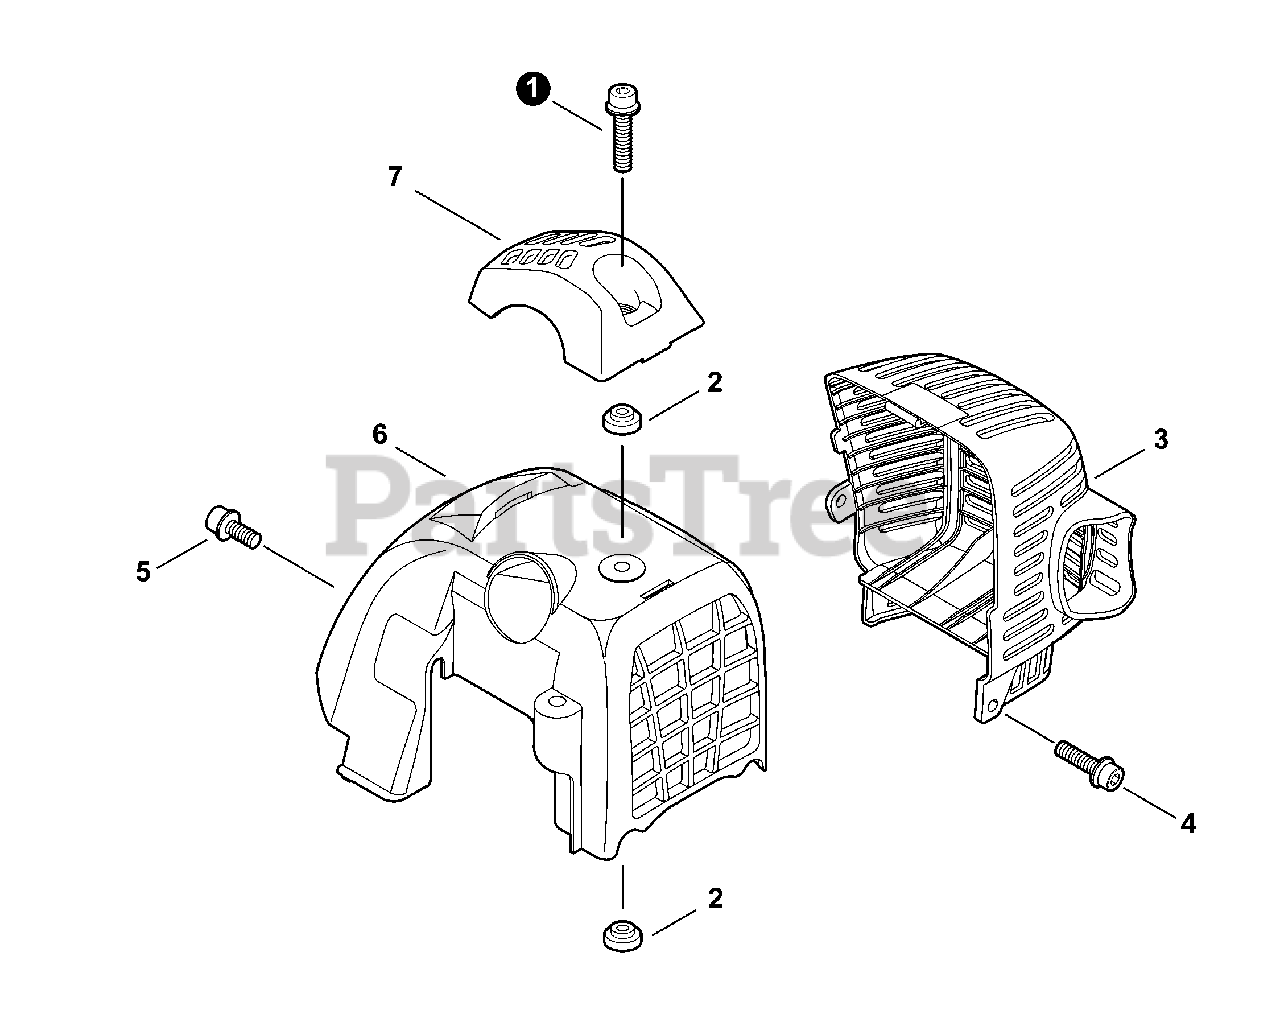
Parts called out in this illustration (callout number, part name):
1	BOLT 5×20
2	COLLAR 5
3	COVER, MUFFLER
4	SCREW 5×16
5	SCREW 5×10
6	COVER, ENGINE
7	GUARD, TOP
